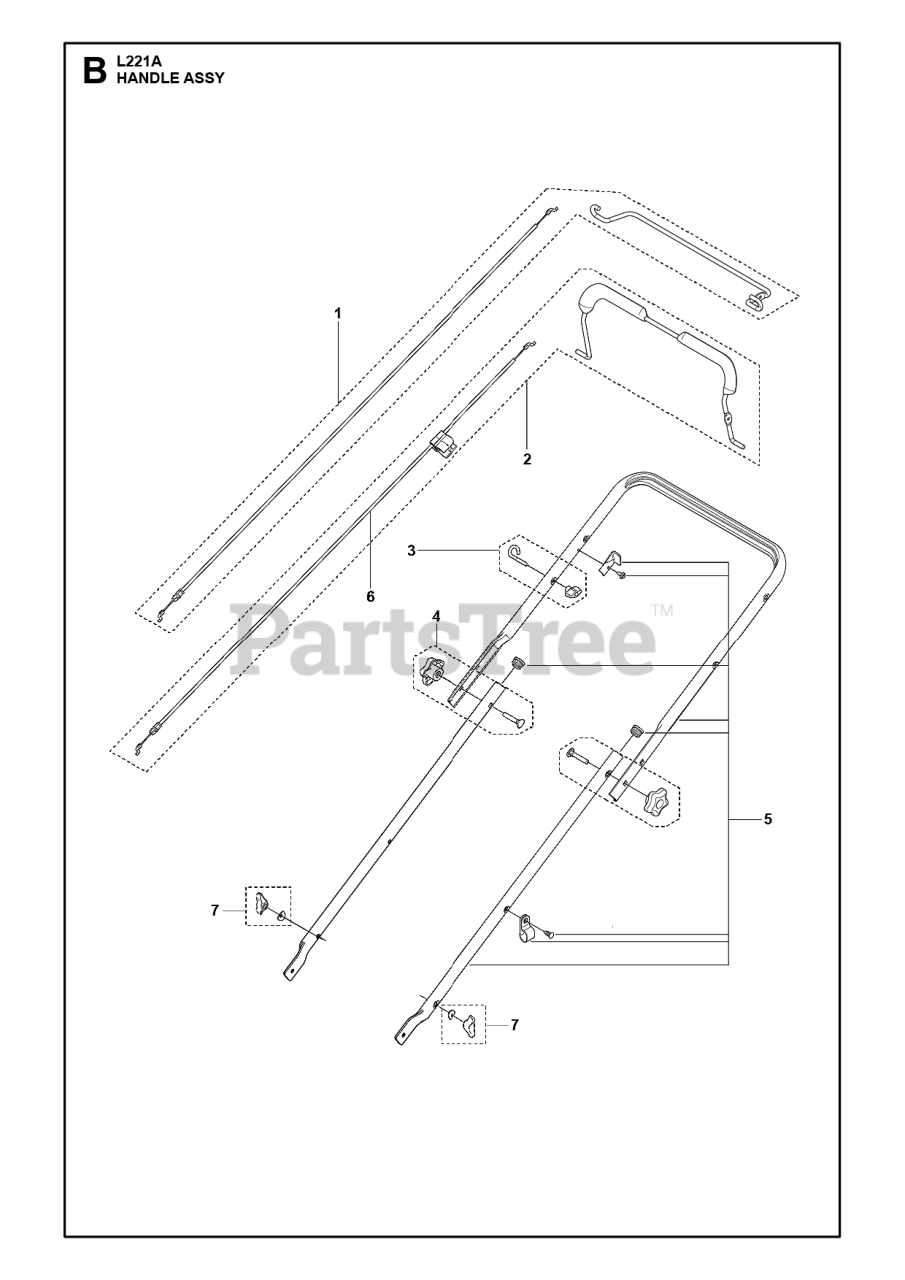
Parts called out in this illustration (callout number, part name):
1	Cables
2	Kits
4	Washers
5	Handles
6	CABLE.MZR.RGD.PLUS.STRT
7	KNOB
